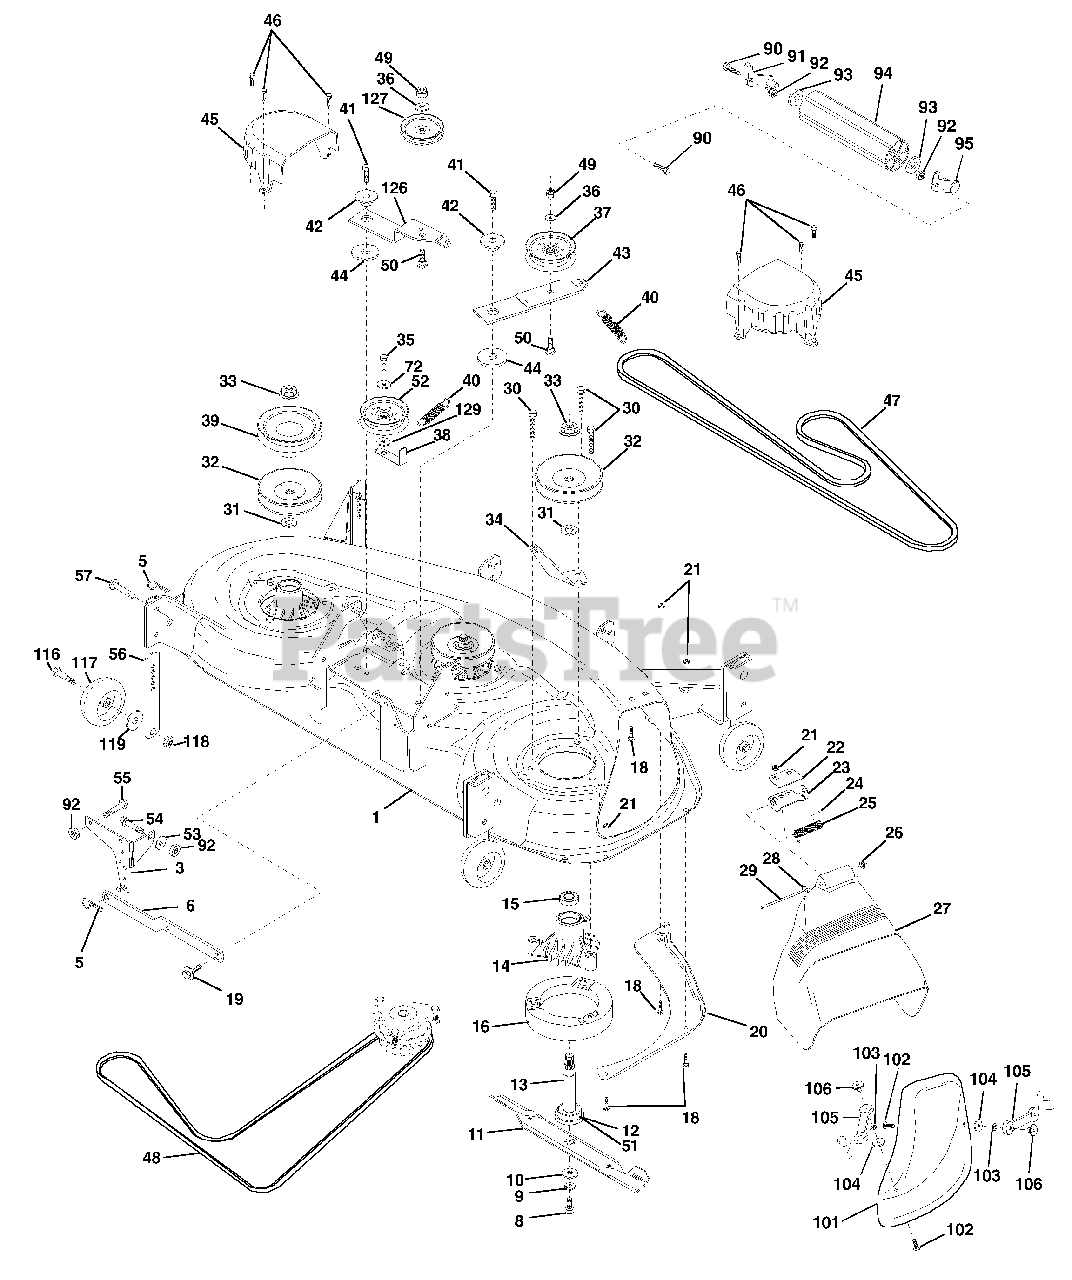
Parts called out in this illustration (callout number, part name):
1	Deck Asm., Mower 46"
3	Bracket Asm., Sway Bar
5	Retainer Spring
6	Arm, Suspension, Rear (Sway Bar)
8	Bolt, Patched 3/8-24 x 1-1/4 Gr. 8
9	Washer, Lock Hvy., Unplated 3/8
10	Washer, Hard Blade, Mower Vented
11	Blade, 46" Mower Deck
12	Bearing, Ball, Mandrel #6204
13	Shaft Asm. w/Lower Bearing
14	Housing, Mandrel
15	Bearing, Ball, Mandrel
16	Stripper, Mower Round
18	Bolt, Carriage 5/16-18 x 5/8
19	Bolt, Hex Head, Shoulder 5/16-18
20	Baffle, Vortex Mower 46"
21	Nut, Crownlock 5/16-18 UNC
22	Stiffener, Bracket
23	Bracket, Deflector
24	Cap, Sleeve
25	Spring, Torsion, Deflector
27	Shield, Deflector Mower
28	Washer 11/32 x 5/8 x 16 Ga.
29	Rod, Hinge
30	Screw, Thdroll Washer Head
31	Washer, Spacer Mower Vented
32	Pulley, Mandrel
33	Nut, Flg. Top Lock Cntr. 9/16
34	Anchor, Spring Deck 46"
35	Screw, Thdroll 3/8-16 x 1-3/4 Tytt
36	Washer 13/32 x 13/16 x 16 Ga.
37	Pulley, Idler, Flat
38	Keeper, Belt, Idler
39	Pulley, Idler, Driven
40	Spring, Secondary 44/46/50 Vent
41	Screw, Thdroll 3/8-16 x 1-1/4 Tytt
42	Spacer, Retainer
43	Arm, Idler Secondary
44	Washer, Hardened
45	Cover, Mandrel Deck
46	Screw, Thdroll. 1/4-20 x 5/8
47	V-Belt, Mower, Secondary
48	V-Belt, Mower, Primary
49	Nut, Crownlock 3/8-16 UNC
50	Bolt, Carriage 3/8-16 x 1-1/2 Gr. 5
51	Washer, Felt
52	Pulley Idler 46 Pri. Drive
53	Washer 13/32 x 13/16 x 12 Ga.
54	Bolt Fin Hex 3/8-16unc x 1 Gr. 5
55	Bolt Rdhd Sqnk 3/8-16 unc x 1
56	Bar Pnt Adjusting Wheel Gauge
57	Pin Head, Rivet
72	Washer 13/32 x 1 x 16 Ga.
90	Bolt, Fin, Hex 3/8-16 unc x 1
91	Bracket, Asm Noseroller, LH
92	Nut, Lock, Hex w/Ins 3/8-16 unc
93	Washer 17/32 x 7/8 x 16 Ga.
94	Roller, Nose 38 & 42
95	Bracket, asm Noseroller RH
101	Cover, Mulching
102	Screw
103	Washer, Lock #10
105	Latch Asm. Bagger
106	Nut, Weld
116	Bolt, Shoulder
117	Gauge Wheel
118	Nut, Centerlock 3/8-16 unc
119	Washer 3/8 x 7/8 x 14 Ga.
126	Arm, Idler, Primary Deck 46"
127	Pulley, Idler, V-Groove Dim. 4.25
